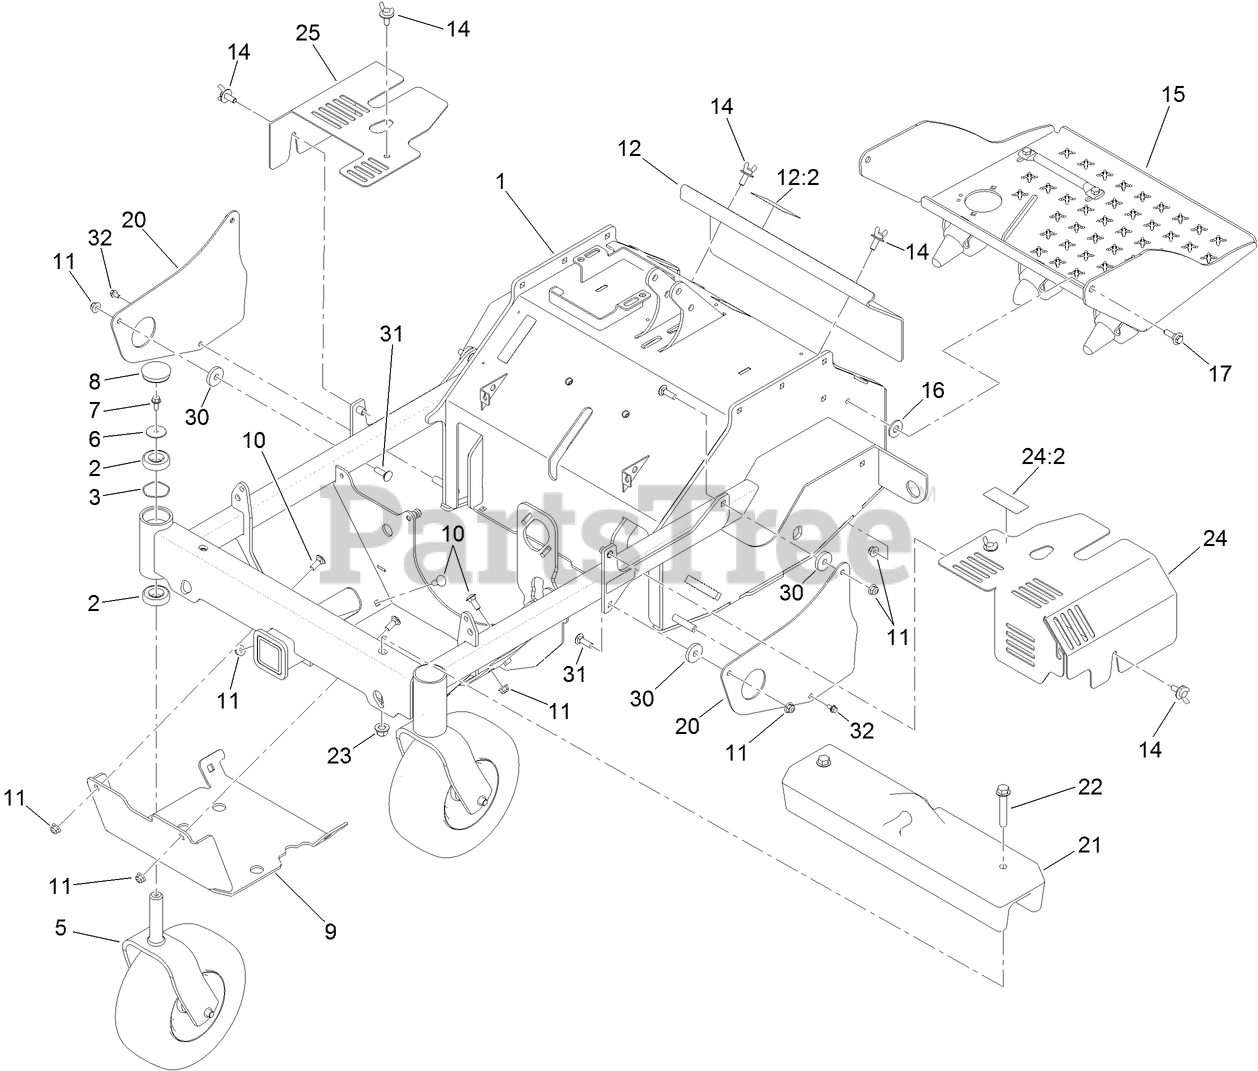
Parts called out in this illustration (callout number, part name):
1	MAIN FRAME ASM
2	BEARING-BALL
3	SPRING
5	FRONT CASTER ASM
6	WASHER-FLAT
7	SCREW-HHF
8	CAP-GREASE
9	GUARD-ENGINE
10	BOLT-CARR
11	NUT-HF, NI
12	ACCESS COVER ASM
12:2	DECAL-OPERATION, TINE GROUND (CE)
14	SCREW-SEMS (3/8-16 X 1)
15	PLATFORM ASM
16	WASHER-FLAT
17	SCREW-SHOULDER, HWH
20	GUARD-CHAIN
21	WEIGHT-FRONT
22	SCREW-HF
23	NUT-LOCK
24	HYDRO-COVER
24:2	DECAL-RELEASE, DRIVE
25	COVER-HYDRO
30	WASHER-CLUTCH
31	BOLT-CARR
32	SCREW-HHF
